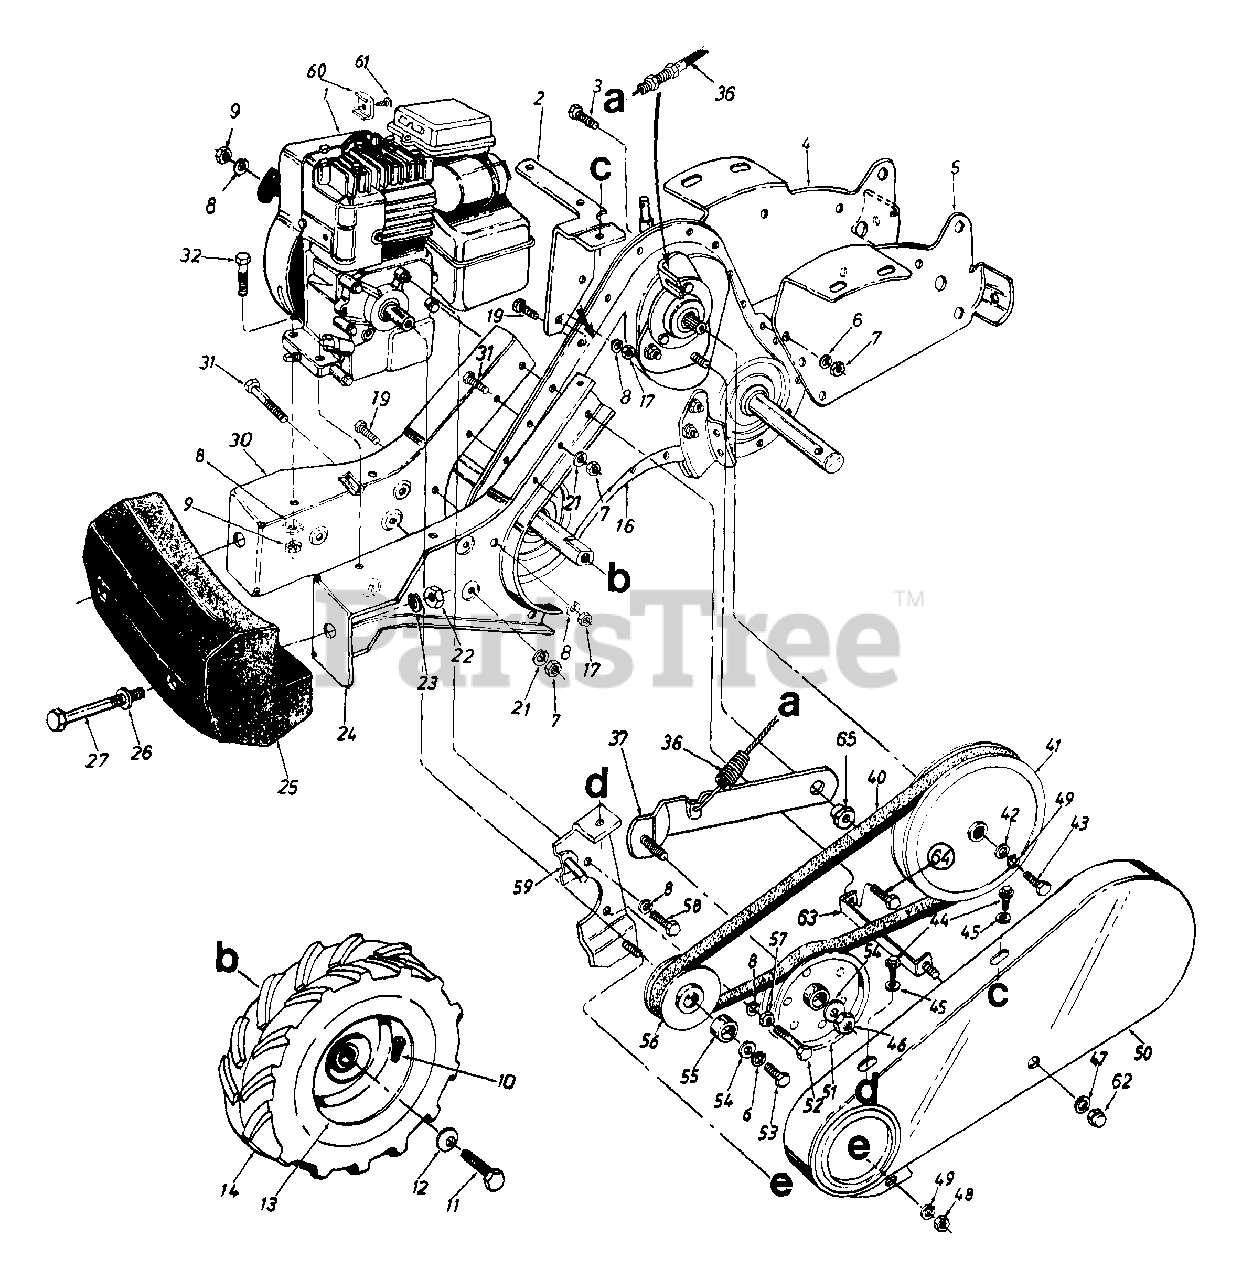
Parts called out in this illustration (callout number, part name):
1	Engine
7	Hex Nut 3/8-16 Thd.
8	L-Wash. 5/16" I.D.
9	Hex Nut 5/16-18" Thd.
10	Air Valve
11	Hex Bolt 5/16-24 x .62" Lg.
12	Bell-Wash..345" I.D. x .88"
13	Wheel Rim Ass'y. Only
14	L.H. Wheel Ass'y. Comp.
17	Hex Nut 5/16-18 Thd.
19	Hex Bolt 5/16-18 x .75" Lg.
21	L-Wash. 3/8" I.D. - H.D.
22	Hex Nut 1/2-13 Thd.
23	L-Wash. 1/2" I.D.
26	Fl-Wash. .510" I.D. x 1.0"
27	Hex Bolt 1/2-13 x 5.00" Lg.
32	Hex Bolt 5/16-18 x 1.50"
36	Clutch Control Cable 46" Lg.
37	Idler Bracket Ass'y.
40	"V"-Belt
41	Fl-Pulley .8" O.D.
42	Fl-Wash. 1/4" I.D. x .93" O.D.
43	Hex Bolt 1/4-28 x .75" Lg.
44	Hex Wash. Hd. S-Tap Scr. 1/4-20 x .50" Lg.
45	Fl-Wash. .281" I.D. x .625"
46	Hex Cent. L-Nut 3/8-24 Thd.
47	Fl-Wash. .266" I.D. x .625" O.D.
48	Hex Nut 1/4-20 Thd.
49	L-Wash. 1/4" I.D.
51	Fl-Idler w/Flanges 3.75" 0.0.
52	Hex Bolt 5/16-24 x 1.75"
53	Hex Bolt 3/8-24 x 1.00" Lg.
54	Fl-Wash. 3/8" I.D. x 1.00"
55	Spacer .758" I.D. x .990"
56	Engine Pulley
57	Hex Nut 5/16-24 Thd.
58	Hex Bolt 5/16-24 x .62" Lg.
61	Hex Sems Scr. 010-32 x .62"
62	Hex Cap Nut 1/4-28 Thd.
63	Belt Cover Bracket Ass'y.
65	Shld. Nut
